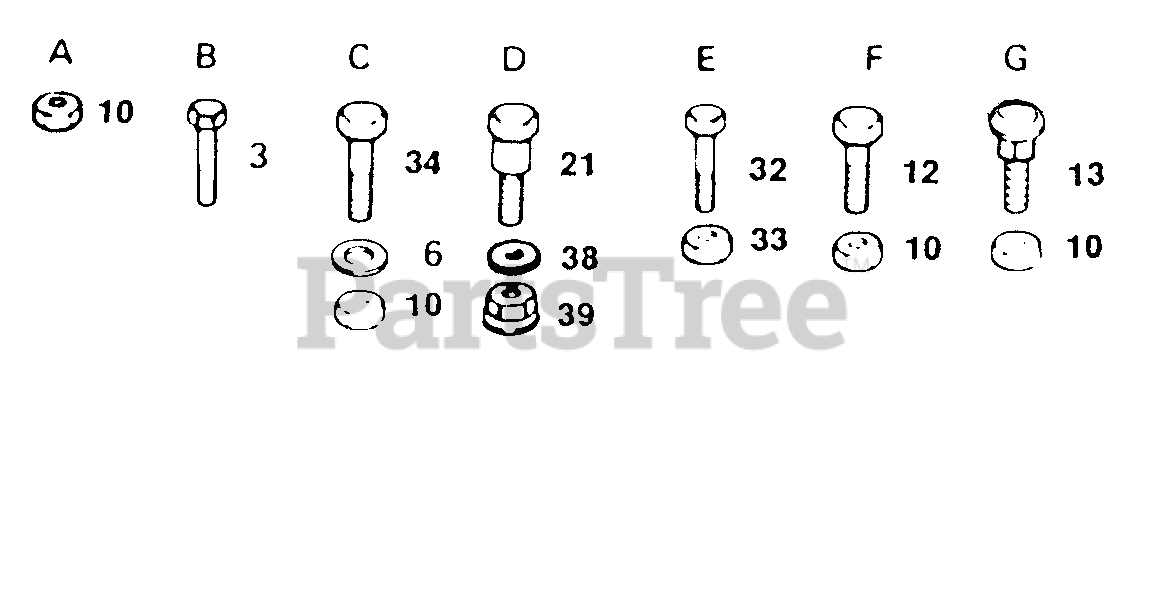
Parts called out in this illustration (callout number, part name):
3	Screw, Tap. Hex Hd. 10-24 x 1/2
6	Washer 13/32 x 13/16 x 12 Ga.
10	Nut, Crownlock 3/8-16
12	Bolt, Hex 3/8-16 x 3/4
13	Bolt, Rd. Hd. Sq Neck 3/8-16 x 3/4
21	Bolt, Shoulder 3/8-16
32	Bolt, Hex 5/16-18 x 3/4
33	Nut, Lock 5/16-18
34	Bolt, Hex 3/8-16 x 1
38	Washer, Spring
39	Nut, Flange Lock 3/8
